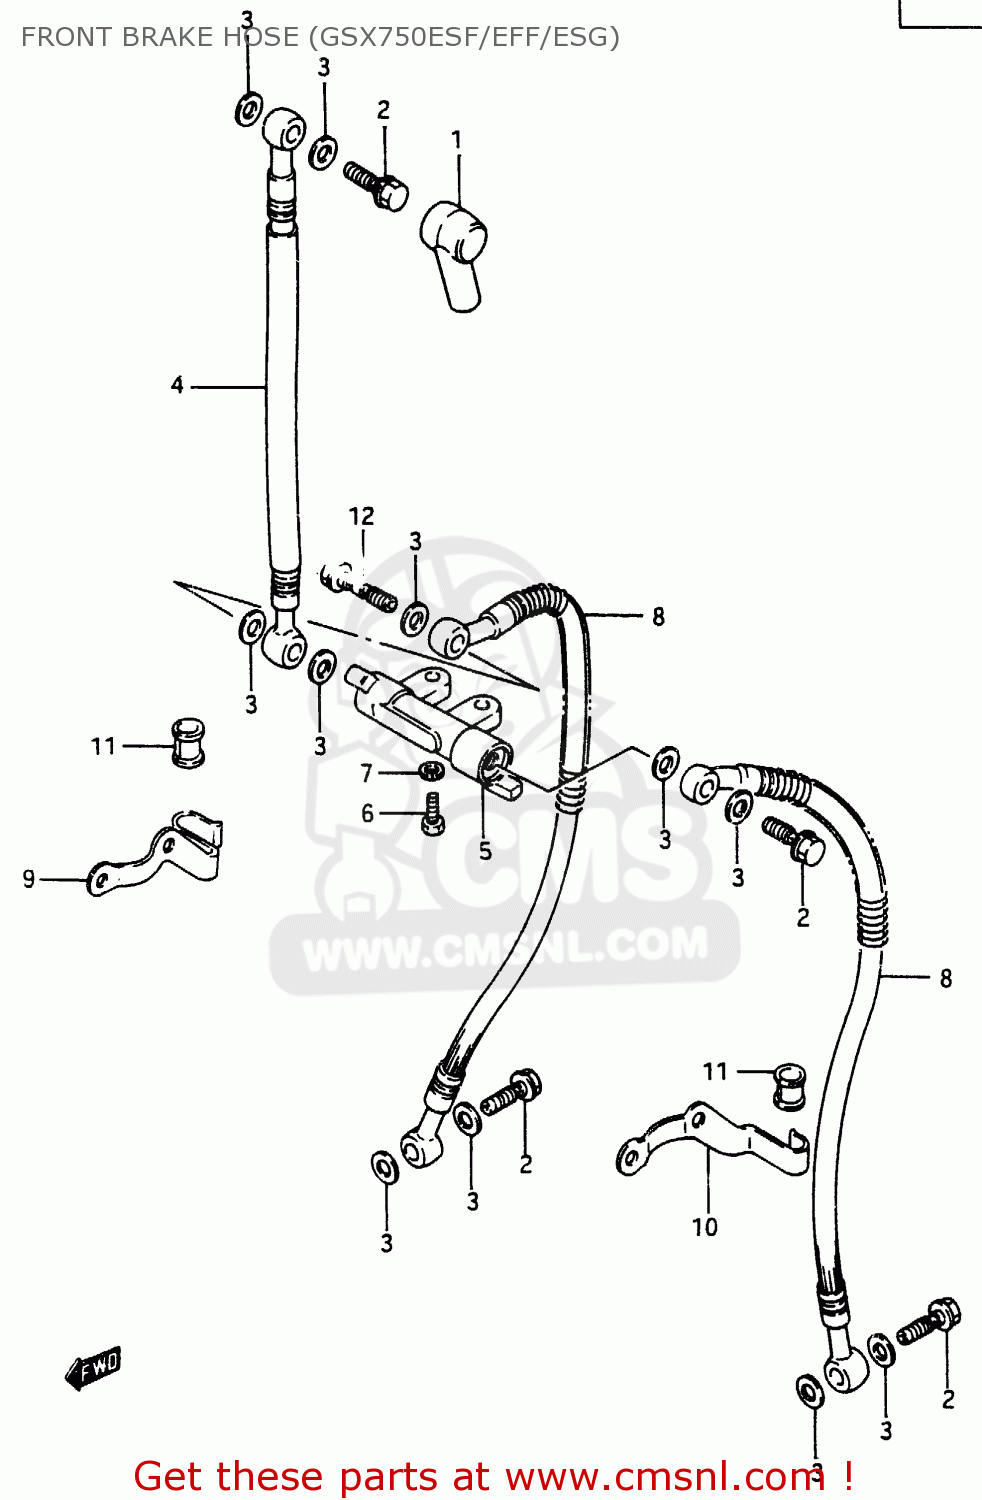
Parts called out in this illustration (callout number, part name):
1	BOOT,MASTER CYLINDER
2	BOLT UNION
3	WASHER(10X15X1.5)
4	HOSE,FR BRAKE NO.1
5	JOINT,BRAKE HOSE
6	BOLT
7	WASHER,LOCK
8	HOSE,FRONT BRAKE NO.2
9	CLAMP, HOSE RH
10	CLAMP, HOSE LH
11	BUSH,BRAKE HOSE GUIDE,NO.2
12	BOLT UNION
